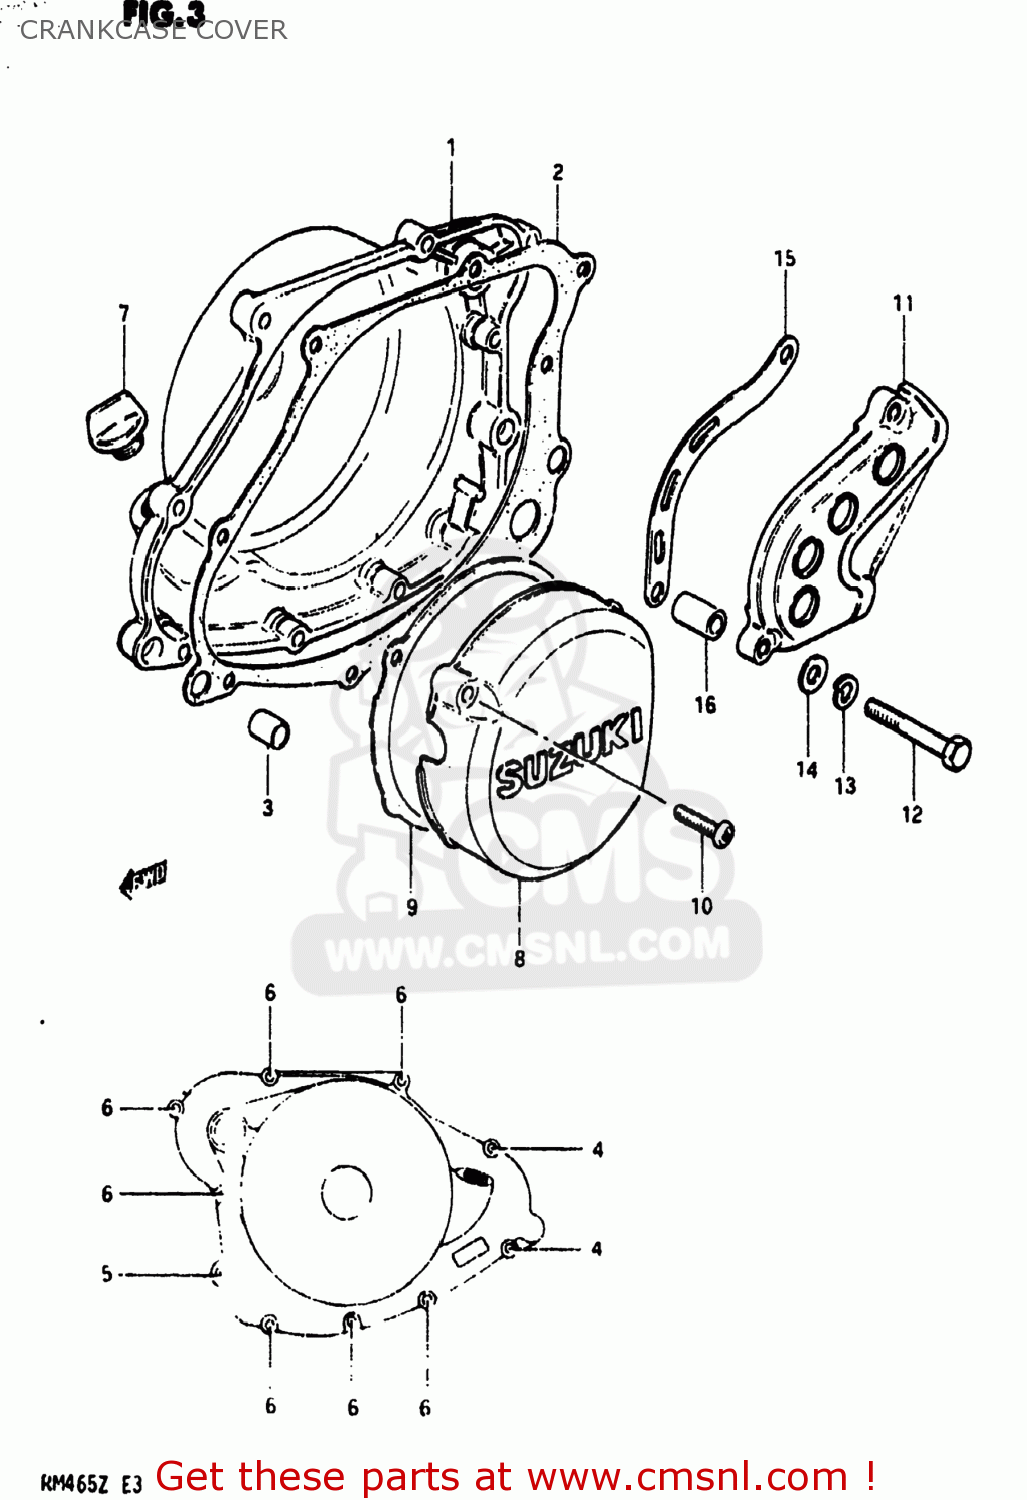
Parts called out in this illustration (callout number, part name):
1	COVER,CLUTCH
2	GASKET,CLUTCH COVER (MCA)
3	PIN
4	SCREW 6X30
5	SCREW (6X45)
6	SCREW
7	PLUG,OIL FILTER
8	COVER,MAGNETO
9	GASKET,MAGNETO COVER (MCA)
10	SCREW
11	COVER,ENGINE SPROCKET
12	BOLT 8X55
13	LOCK WASHER
14	WASHER
15	PLATE,FR CHAIN GUIDE
16	SPACER(8.6X16X24)
